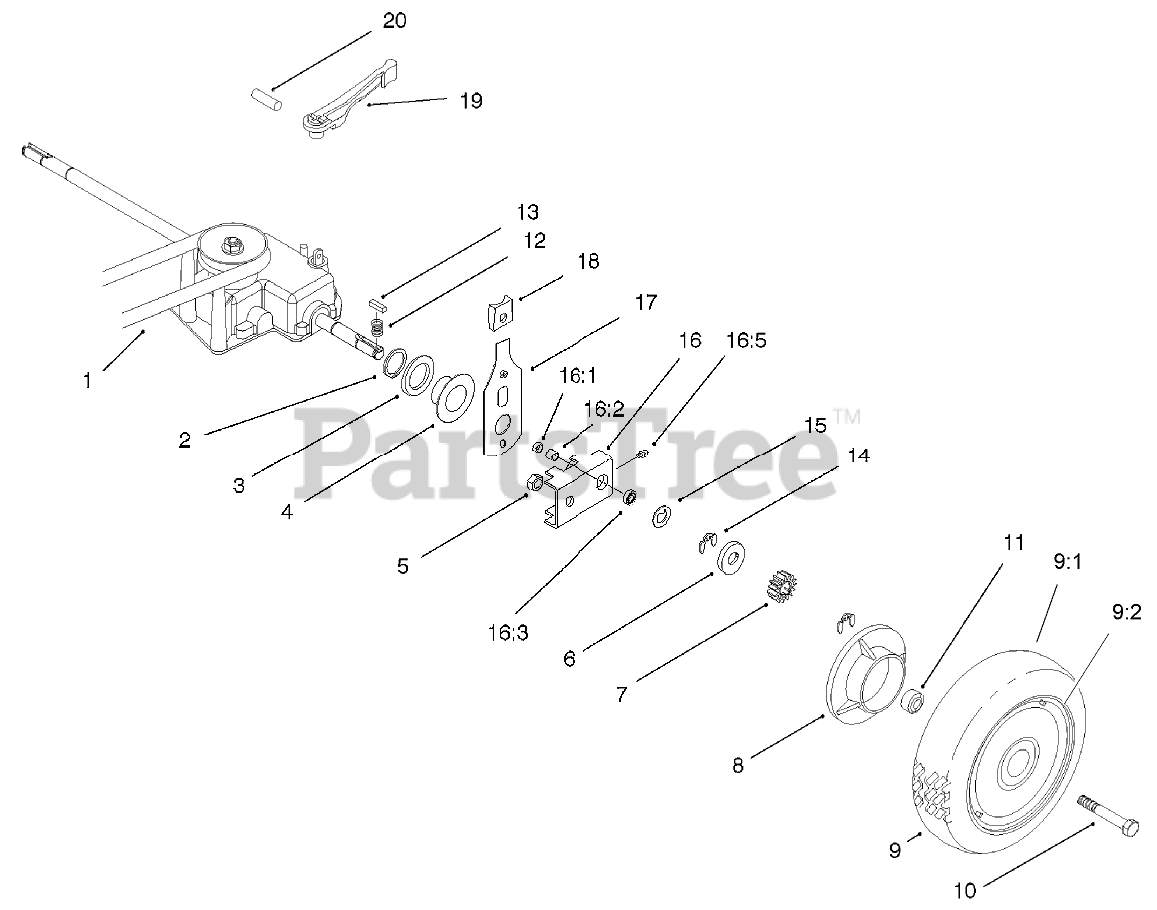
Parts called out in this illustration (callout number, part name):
1	V-BELT
2	RING-RETAINING
3	WASHER
4	CAP-END
5	NUT-LOCK, CONE
6	WASHER-THRUST, OUTER
7	GEAR-PINION
8	COVER-WHEEL
9	Wheel And Tire ASM
9:2	Wheel ASM
10	SCREW-HH
11	SPACER-COVER, WHEEL
12	SPRING-COMPRESSION
14	RING-RETAINING
15	WASHER-THRUST, OUTER
16	PIVOT ARM ASM
16:1	SEAL-OIL
16:2	BEARING-ROLLER
16:3	BEARING-WHEEL
17	REAR SPRING ARM ASM
18	KNOB-ARM
19	LEVER-SHIFT
20	PIN-COIL
99	GRASS BAG ASM
